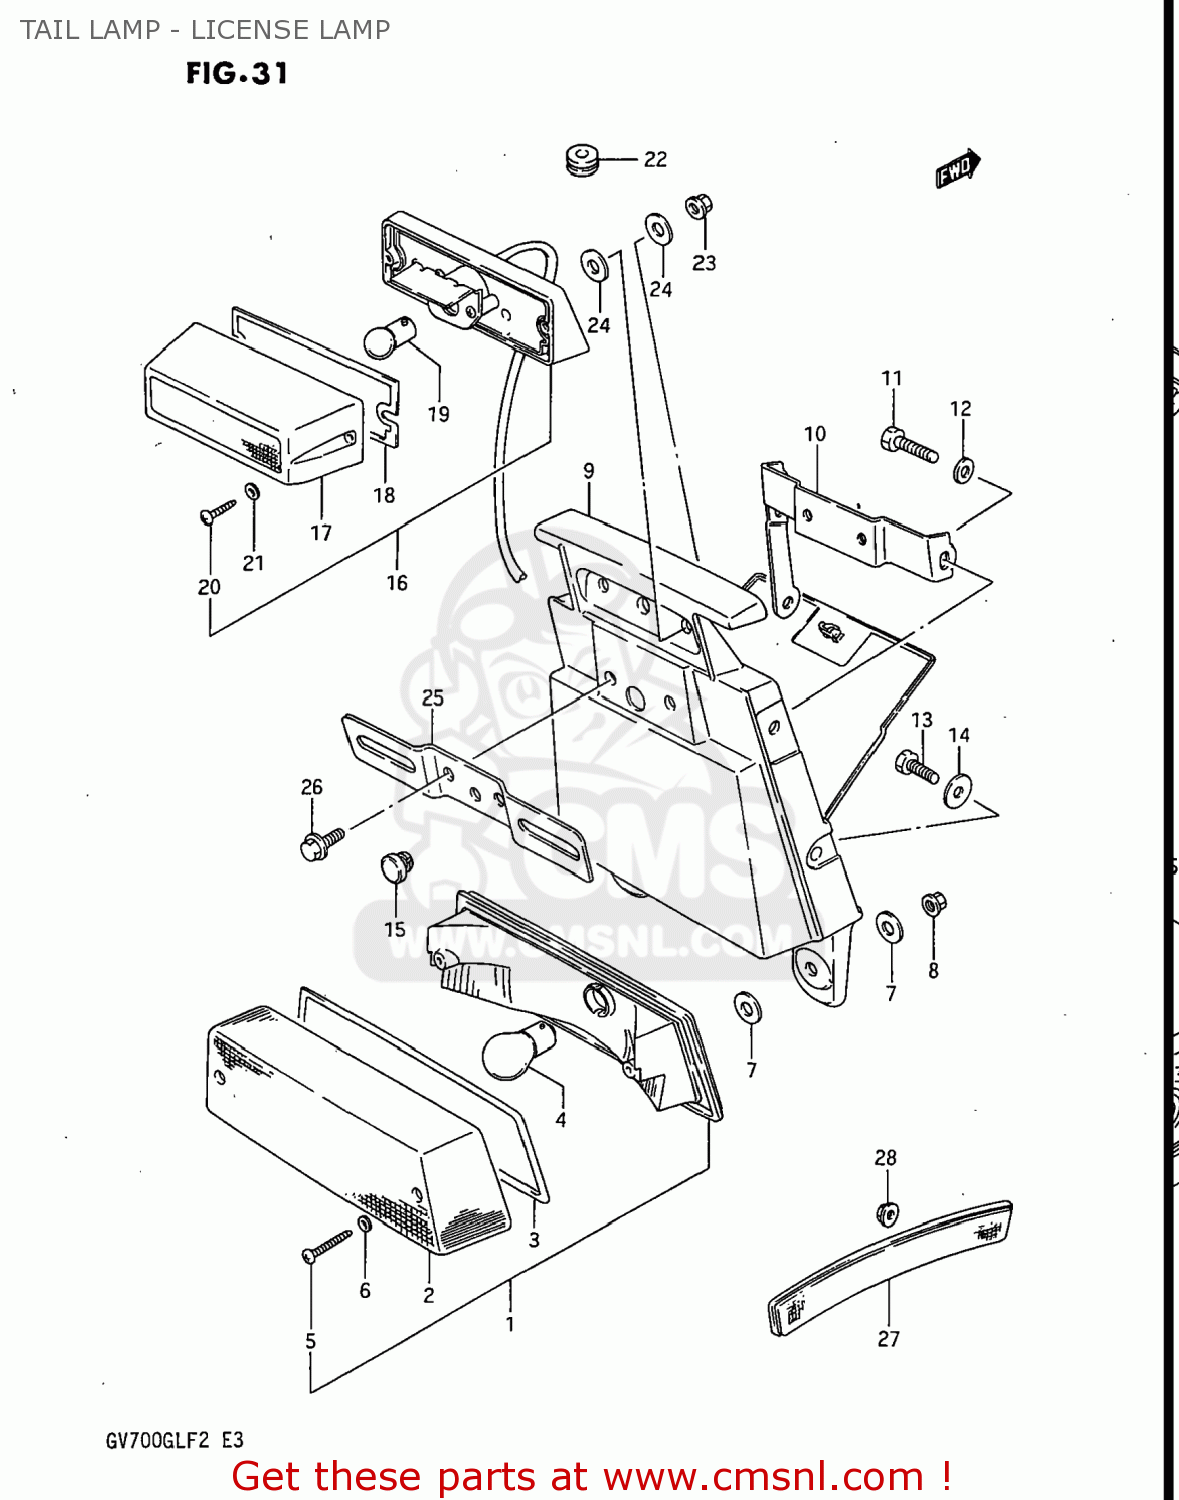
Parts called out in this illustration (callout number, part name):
1	LAMP ASSEMBLY,REAR COMBINATION
2	LENS,REAR COMBINATION LAMP
3	GASKET,REAR COMBINATION LAMP LENS
4	BULB(12V23/8W,TOKAI DENSO)
5	SCREW
6	GASKET (NAS)
7	WASHER
8	NUT
9	UNIT COMP,REAR
10	REINFORCEMENT,REAR COVER
11	BOLT
12	WASHER, LOWER
13	BOLT,M6X1X20
14	WASHER
15	CUSHION
16	LAMP ASSEMBLY,LICENSE
17	LENS COMP,LICENSE
18	GASKET,LICENSE LAMP
19	BULB
20	SCREW
21	GASKET (NAS)
22	GROMMET,REAR COMBINATION LAMP
23	NUT
24	WASHER
25	PLATE,RR LICENSE
26	BOLT
27	REFLECTOR,REFLEX
28	NUT
